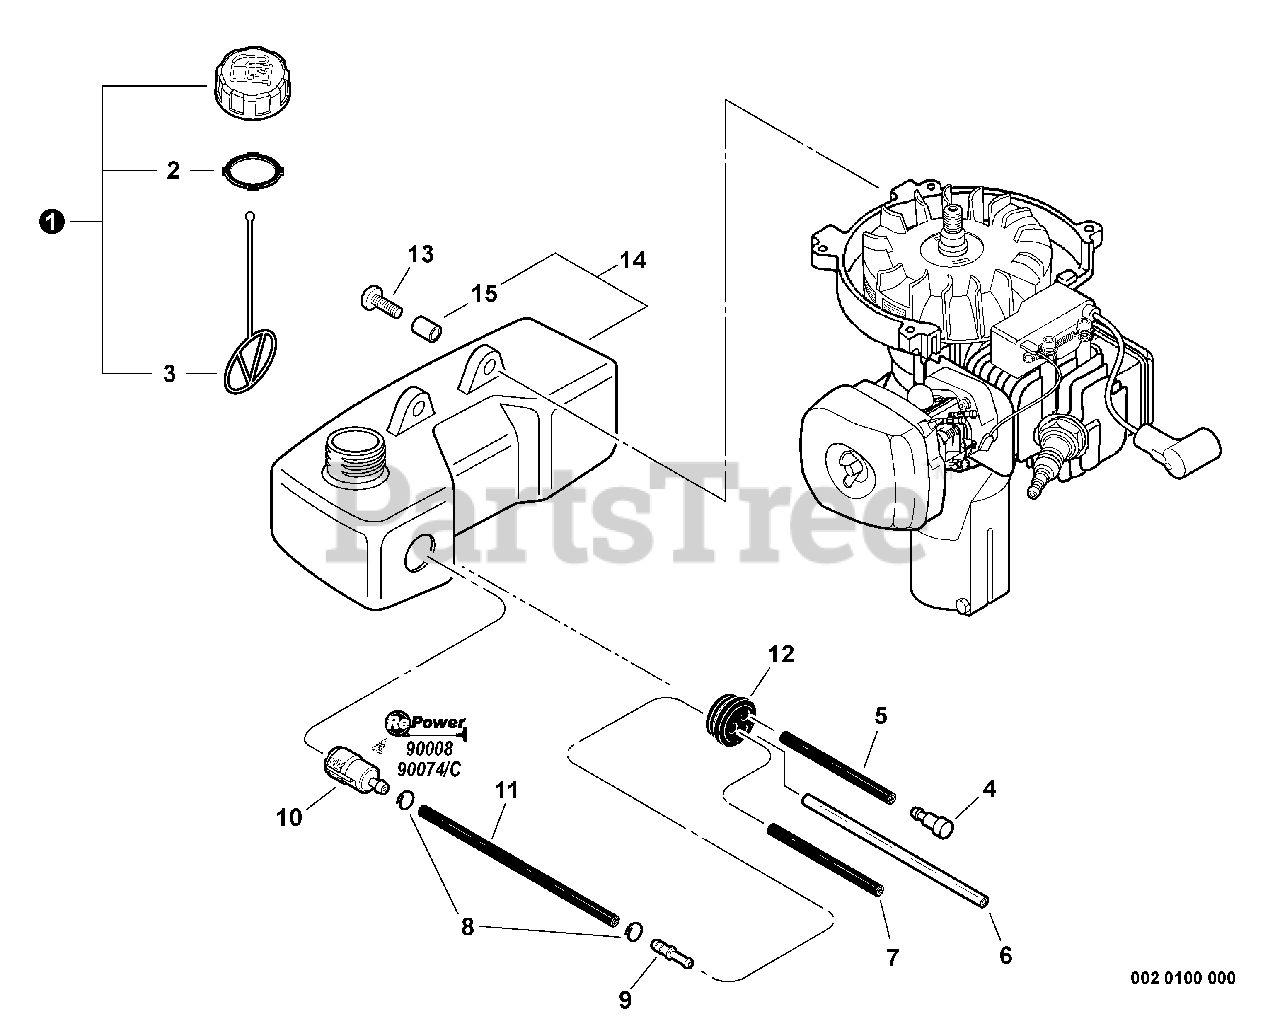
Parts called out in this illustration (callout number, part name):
1	CAP ASSY - ORANGE
2	GASKET, CAP
3	CONNECTOR, CAP
4	VENT, FUEL TANK
5	PIPE - 3X5X70 -- BLACK
6	PIPE - 3X6X110 -- CLEAR
7	PIPE - 3X5X70 -- BLACK
8	CLIP - 6
9	CONNECTOR, PIPE
10	FILTER, FUEL
11	PIPE - 3X5X140 -- BLACK
12	GROMMET
13	SCREW - 5X16 -- TAPPING
14	FUEL TANK ASSY
16	RePower TUNE-UP KIT
17	RePower FILTER KIT
